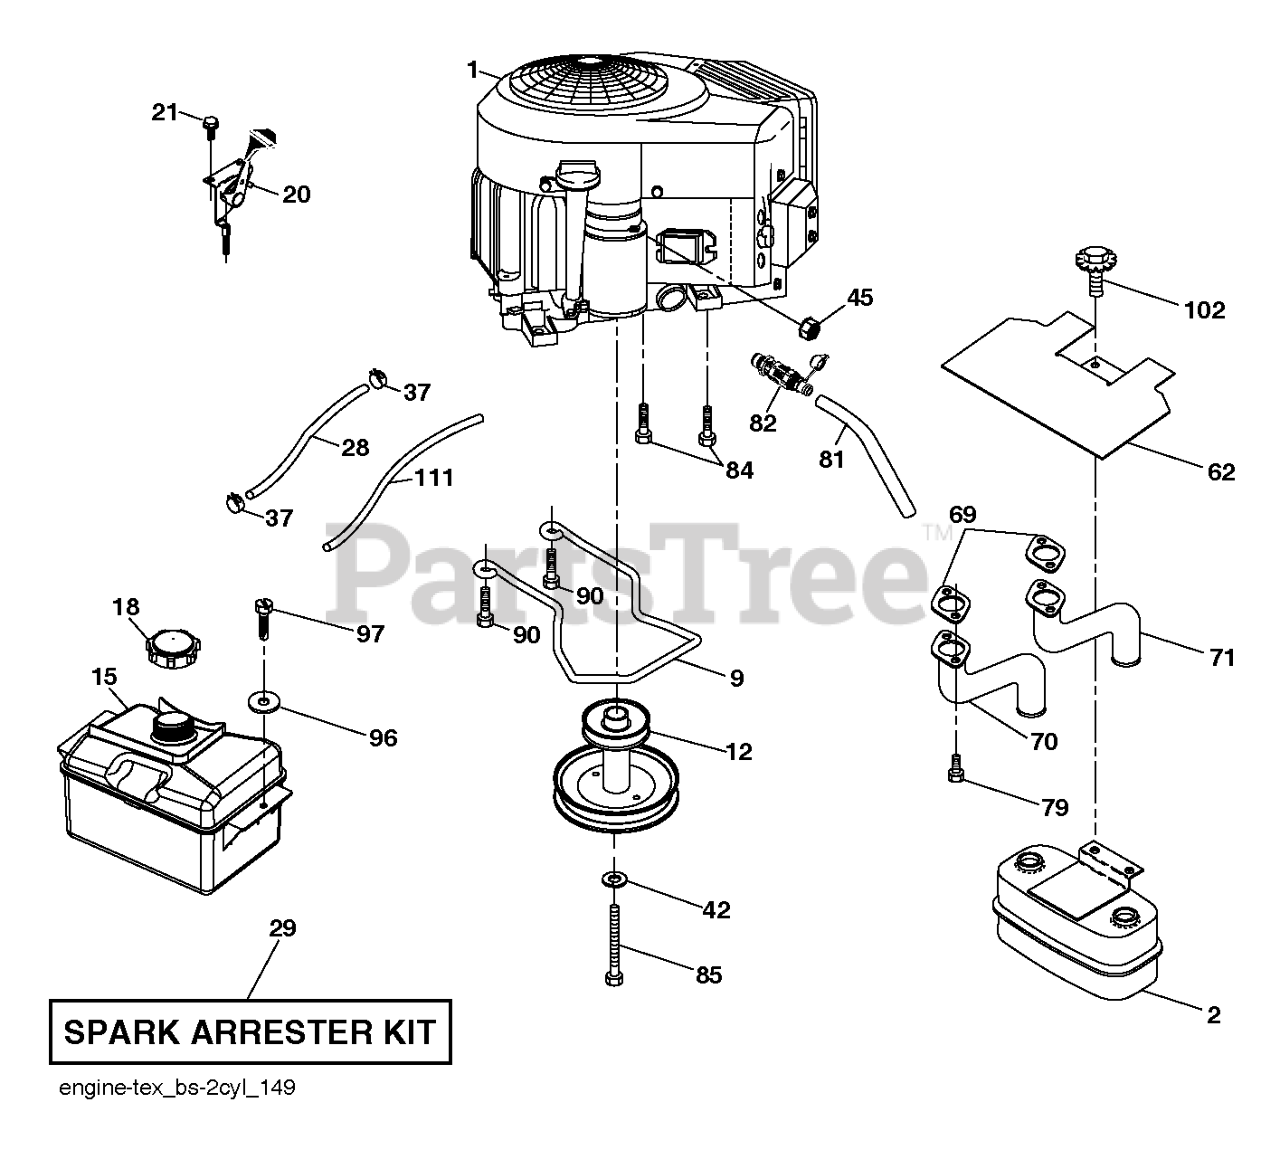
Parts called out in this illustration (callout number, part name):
2	MUFFLER.ASM.TWIN.MNTG.BRACKET
9	KEEPER.BELT.ENG.3.25"2BOLT.PNT
12	PULLEY.ENGINE.5.0.PD
15	TANK.ASM.FT.2.5GAL.W/CAP.EPA17
18	CAP.FUEL.2 WAY VENT
20	THROTTLE.COBRA.38"READSTART.BK
21	SCREW.#10 X 0.750.BOS (2 2)
28	LINE.FUEL.20"FRONT.EMI
29	Arrester, Spark (Optional equipment) (AYP part number)
37	Clamp Hose Black (AYP part number)
42	WASHER 7/16 LOCK
45	Nut Keps Hex 1/4 - 20 UNC (AYP part number)
62	SHIELD.HEAT.MUFFLER
69	REPL BY 532 27 22-93
70	EXHAUST.TUBE.LH.BS/TWIN
71	EXHAUST.TUBE.RH.B&S.TWIN.INTEK
79	SCREW.SOCKET.HEAD.5/16-18
81	TUBE, DRAIN OIL ASM.
82	VALUE.OIL.DRAIN
84	SCREW.3/8-16
85	Speed Clip
90	SCREW 3/8-16X1
96	Washer 9/32 x 7/8 x 16 Gauge (AYP part number)
97	SCREW HEXWSHR 1/4-20X3/4
102	SCREW
111	RP PURGE LINE
